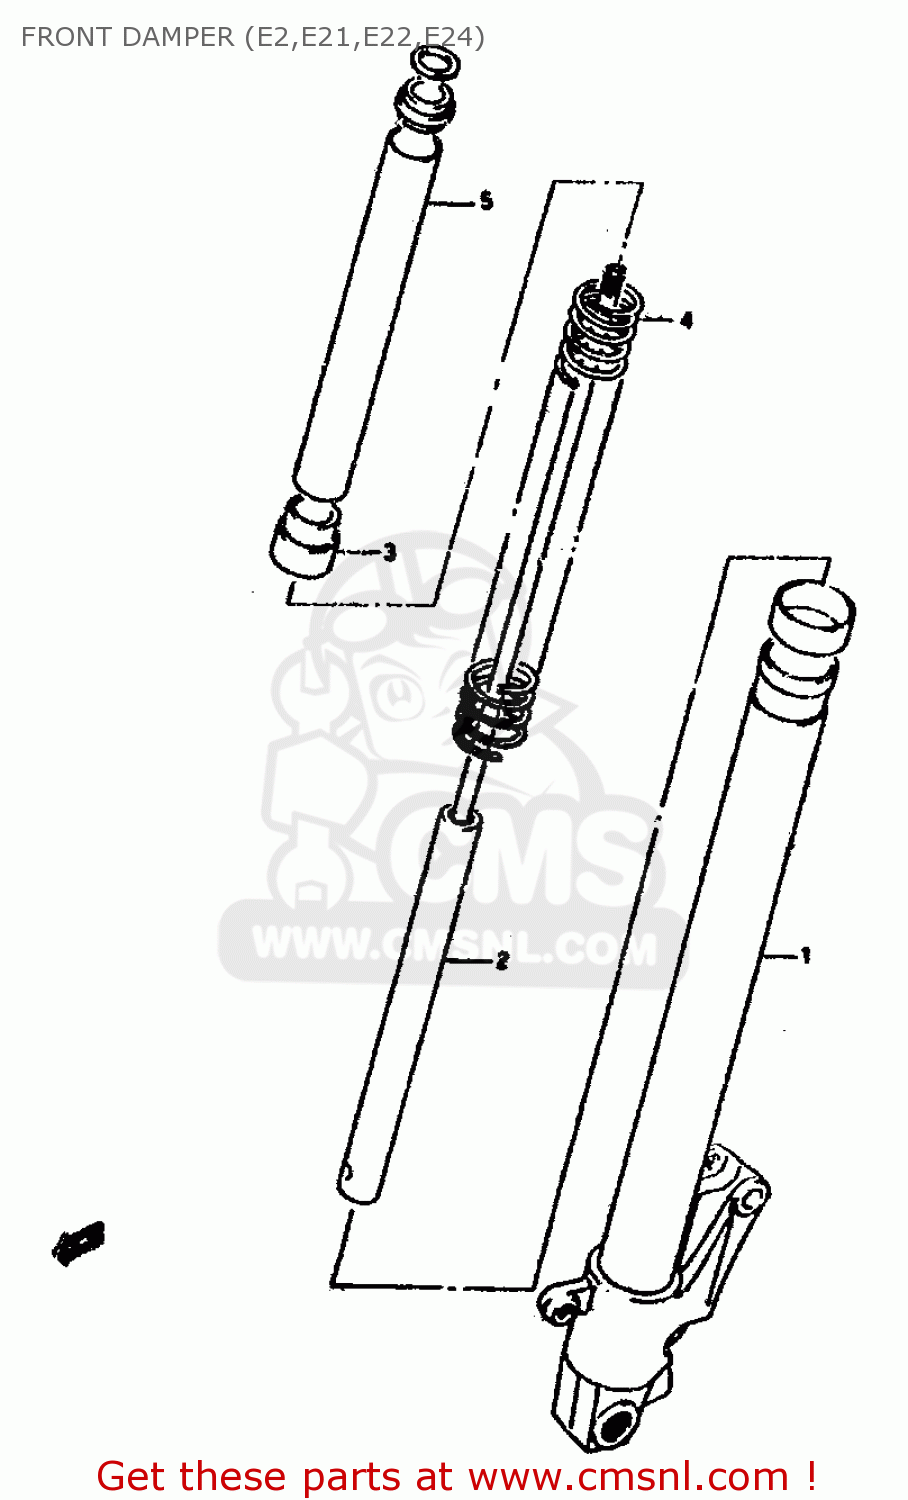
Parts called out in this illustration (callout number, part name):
1	DAMPER ASSY, RH
2	DAMPER, FRONT
3	JOINT,SPRING UPR
4	SPRING, MAIN
5	SPACER,SPRING
